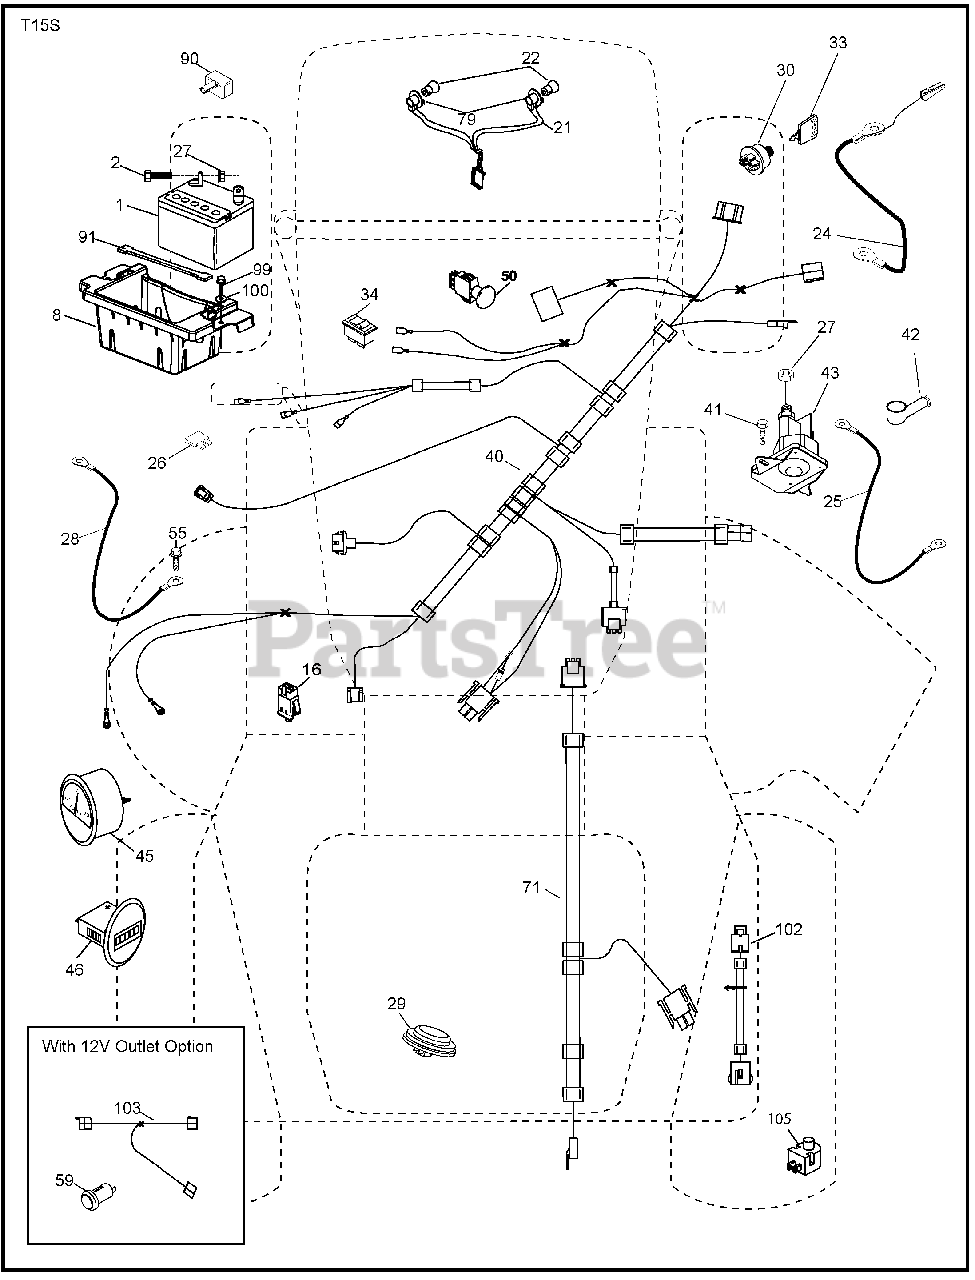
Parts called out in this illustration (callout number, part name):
1	Battery
2	Bolt Hex Head 1/4-20 x 3/4
8	Box Battery
16	Switch Interlock Push-In
21	Harness Socket Light w/4152J
22	Bulb Light
24	Cable Battery
25	Cable Starter
27	Nut Keps Hex 1/4-20 unc
28	Cable, Ground
29	Switch, Seat
30	Switch, Ign
34	Switch Light / Reset
40	Harness Ign. Dash
41	Screw Thd Cut 1/4-20 x 1/2
42	Cover, Terminal
43	Solenoid
45	Ammeter Gauge Round
46	Gauge Servicereminder Hrmtr
50	Switch PTO
55	Screw Thdrol 5/16-18 x 3/4 TYTT
59	Outlet 12-Volt
71	Harness Ign.
79	Socket Asm Bulb Twistlock
81	Relay Harness Sealed
90	Cover Terminal
91	Strap Battery Mount
99	Screw Hexwsh Thdrol 1/4-20 x 3/4
100	Washer 9/32 x 7/8 x 16 Ga.
102	Harness Pigtail
103	Harness 12-Volt Pigtail
105	Switch Reverse TT Pedal Control
